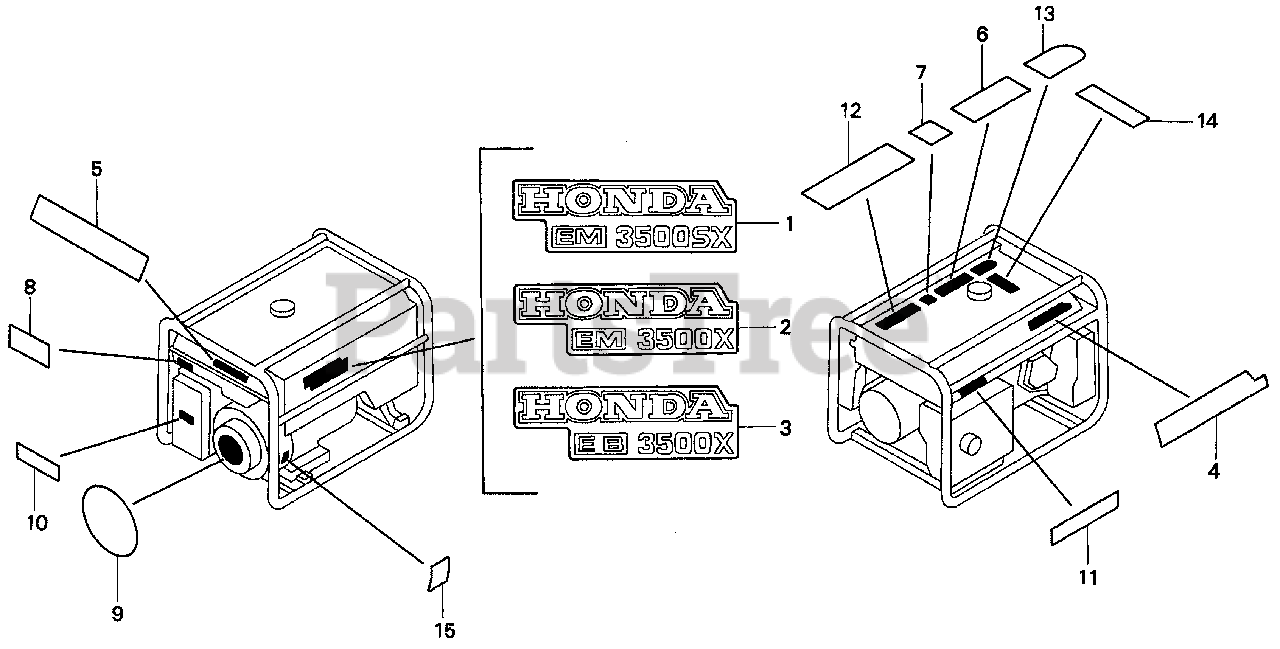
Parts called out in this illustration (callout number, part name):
2	EMBLEM (NOT AVAILABLE)
4	MARK, HONDA (NOT AVAILABLE)
5	PLATE, CAUTION
6	LABEL, RAIN WARNING (ENGLISH)
7	MARK, CAUTION (ENGLISH/FRENCH)(SPANISH)
8	MARK, CHOKE
9	MARK, OIL ALERT (NOT AVAILABLE)
11	MARK, EX. CAUTION (ENGLISH/FRENCH)
12	MARK, CAUTION (CO)(ENGLISH/FRENCH)(SPANISH)
13	LABEL, CONNECT WARNING (ENGLISH)
14	MARK, FUEL METER
15	MARK, OIL CAUTION
